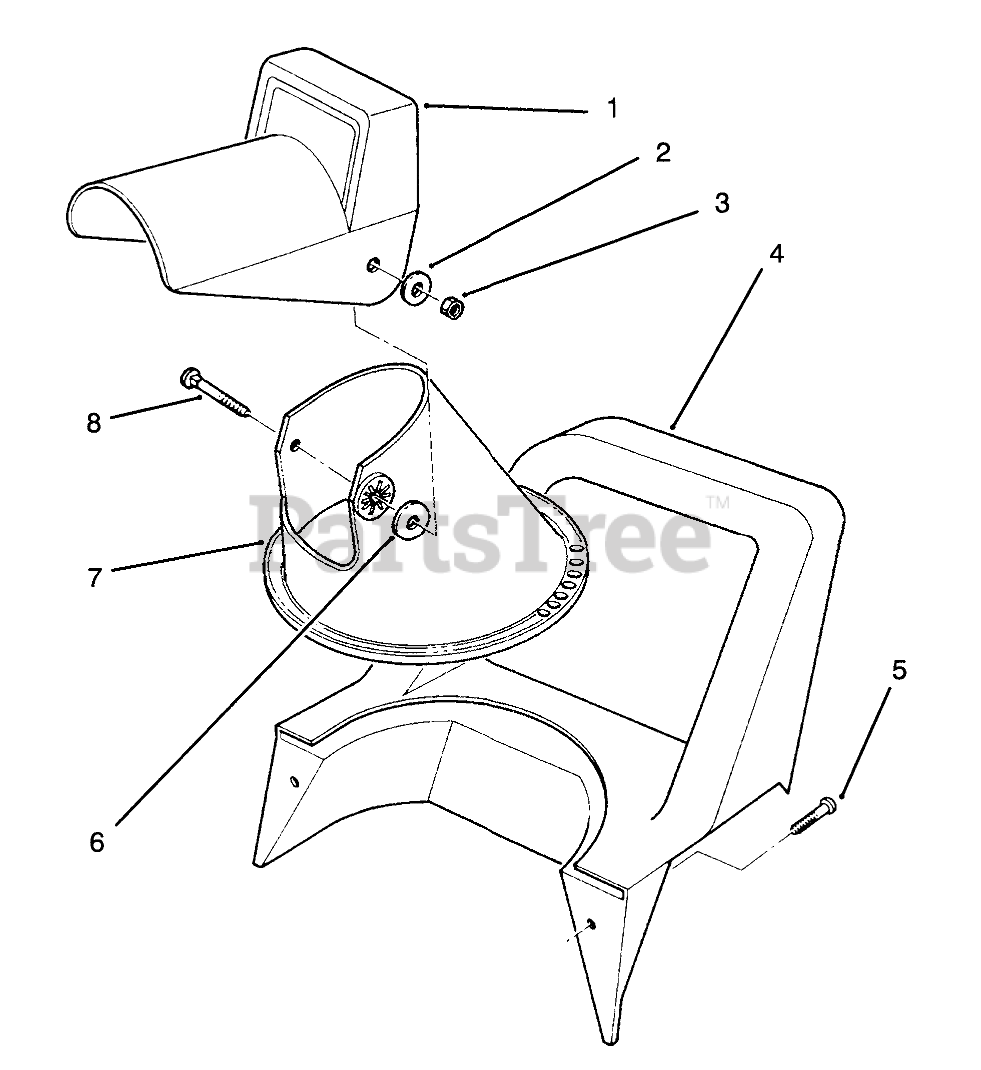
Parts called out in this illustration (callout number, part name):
1	Chute-Deflector
2	WASHER-FLAT
3	NUT-LOCK, NI
4	Handle-Middle
5	Screw
6	WASHER-RUBBER
7	Chute-Lower
8	BOLT-CARR
